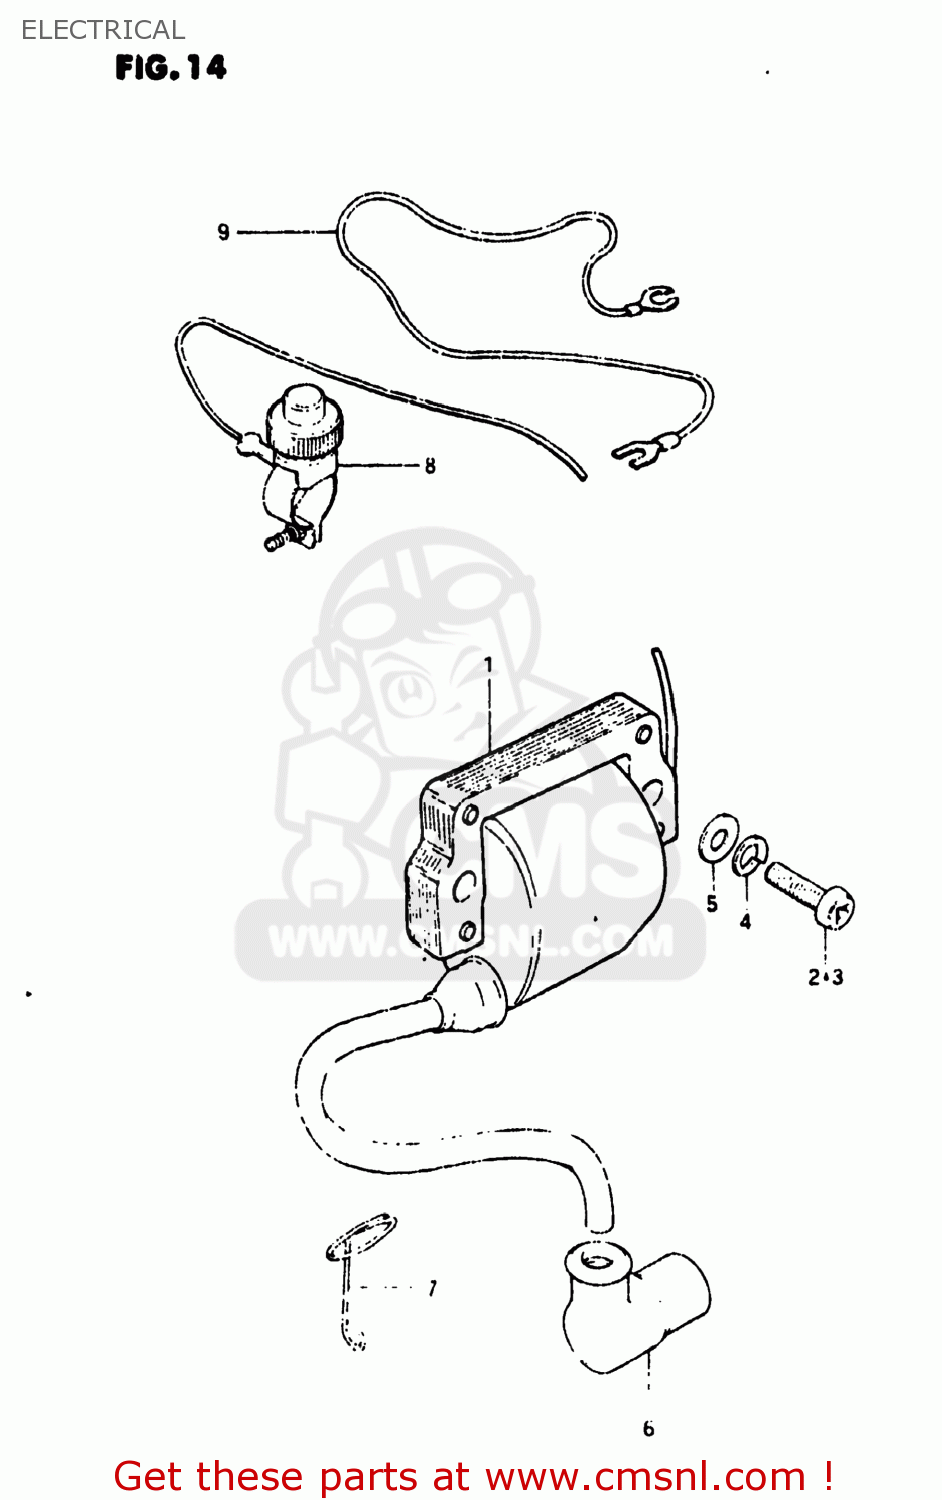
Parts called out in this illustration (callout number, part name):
1	COIL ASSEMBLY,IGNITION
2	SCREW
3	SCREW
4	LOCK WASHER
5	WASHER
6	CAP,SPARK PLUG
7	CLIP
8	SWITCH ASSEMBLY
9	WIRE
